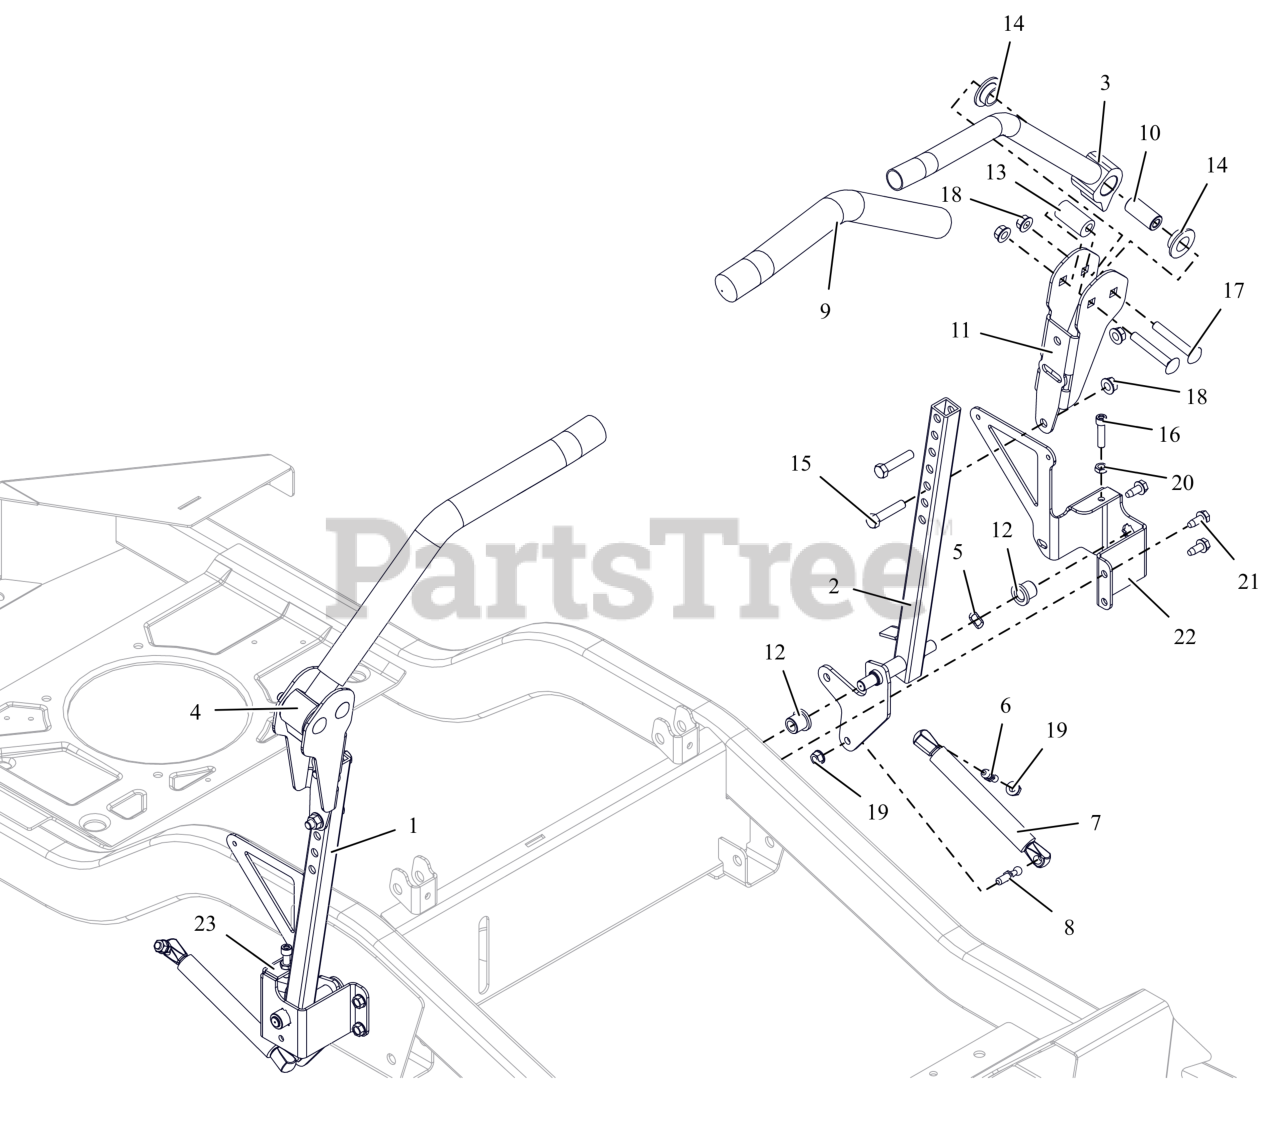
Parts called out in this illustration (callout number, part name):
1	WLDMT, STEERING RH (RED)
2	WLDMT, STEERING -LH (RED)
3	WLDMT, CONTROL HANDLE-LH (RED)
4	WLDMT, CONTROL HANDLE-RH (RED)
5	WAVE WASHER .531X.781X.125FH
6	STUD- BALL
7	DAMPER
8	STUD-BALL-THREADED
9	GRIP, HANDLEBAR
10	SPACER, STEERING ARM
11	BRKT, ADJ UPPER CONTROL ARM (RED)
12	BHSG-FLG .500X.750X.750X.125
13	BSHG, ECCENTRIC.406X.875X1.625
14	BSHG-FLG .762X1.48X.44 NYL
15	BLT, HEX .38-16X1.75 G5 ZCC
16	SCR, SKH .312-18X1.25 GR8 ZC120
17	BLT, RHSSN.38-16X2.50 G5 ZCC
18	NUT-LK-TOP-FLG .38-16 ZC120
19	NUT,LK-CTR-FLG .31-18 GF ZCC
20	NUT-JAM .312-18 G2 ZCC
21	SCR,TAP .312-18X.75 HWH TR ZCC
22	BRKT, STEERING ARM MOUNTING -LH (RED)
23	BRKT, STEERING ARM MOUNTING- RH (RED)
